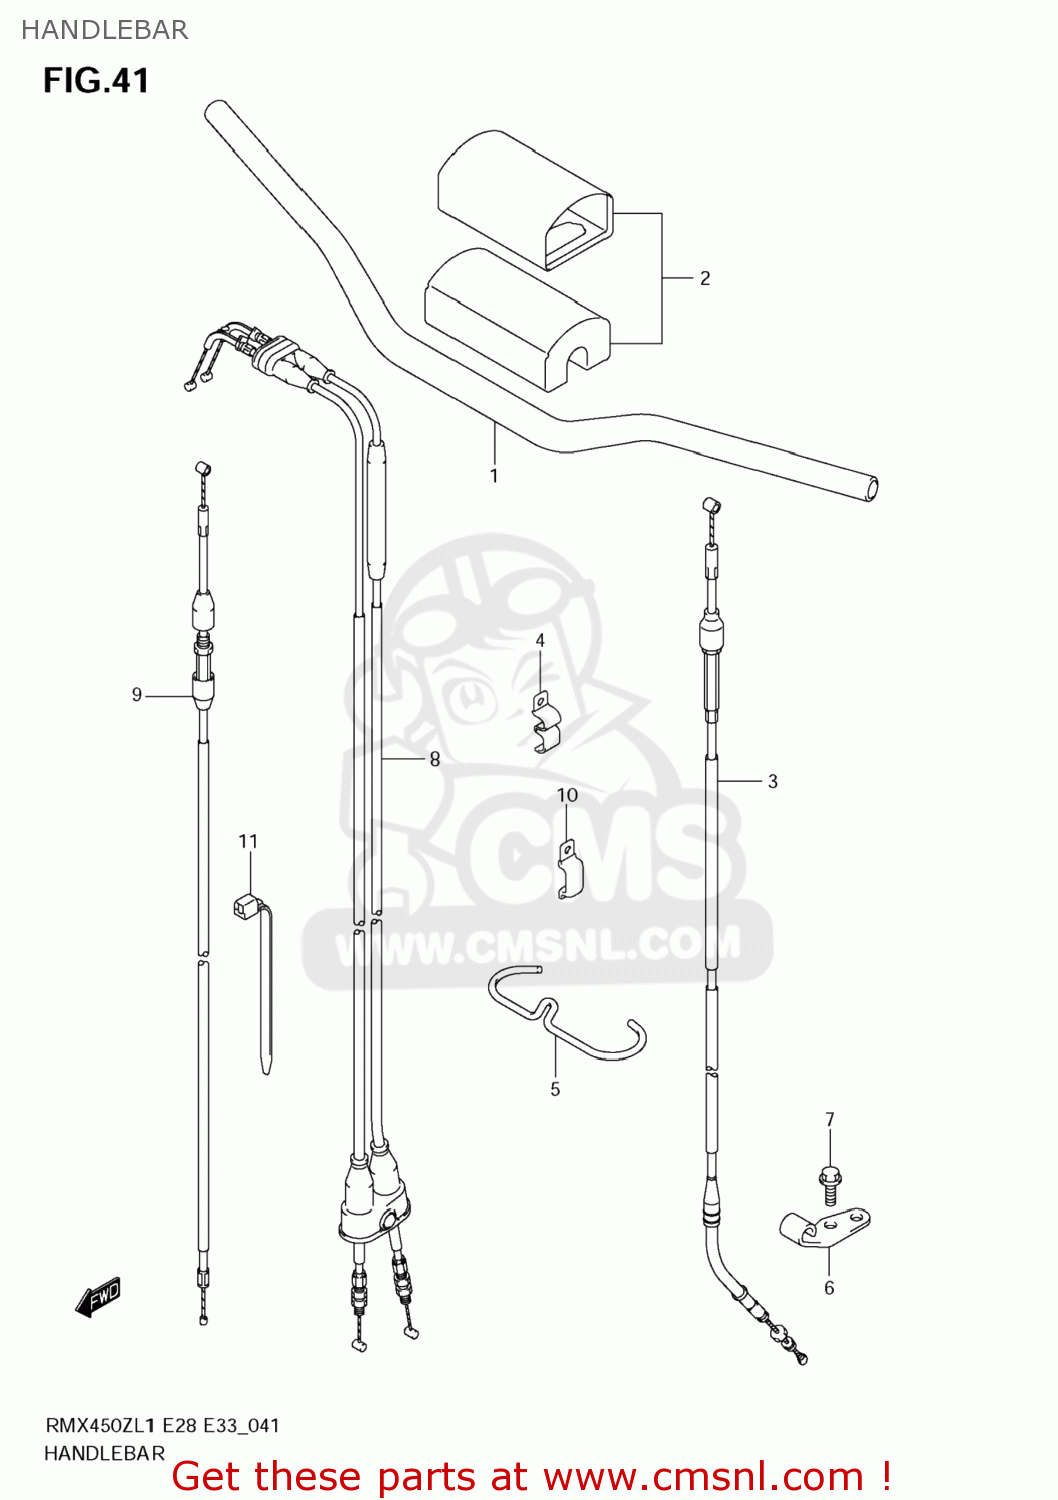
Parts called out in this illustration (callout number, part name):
1	HANDLEBAR
2	PAD SET,HANDLEBAR (NAS)
3	CABLE ASSY,CLUTCH
4	CLAMP,CABLE
5	GUIDE,CABLE
6	STOPPER,CLUTCH CABLE
7	BOLT
8	CABLE SET,THROTTLE
9	CABLE ASSY,HOT STARTER
10	CLAMP
11	CLAMP(L:95)
